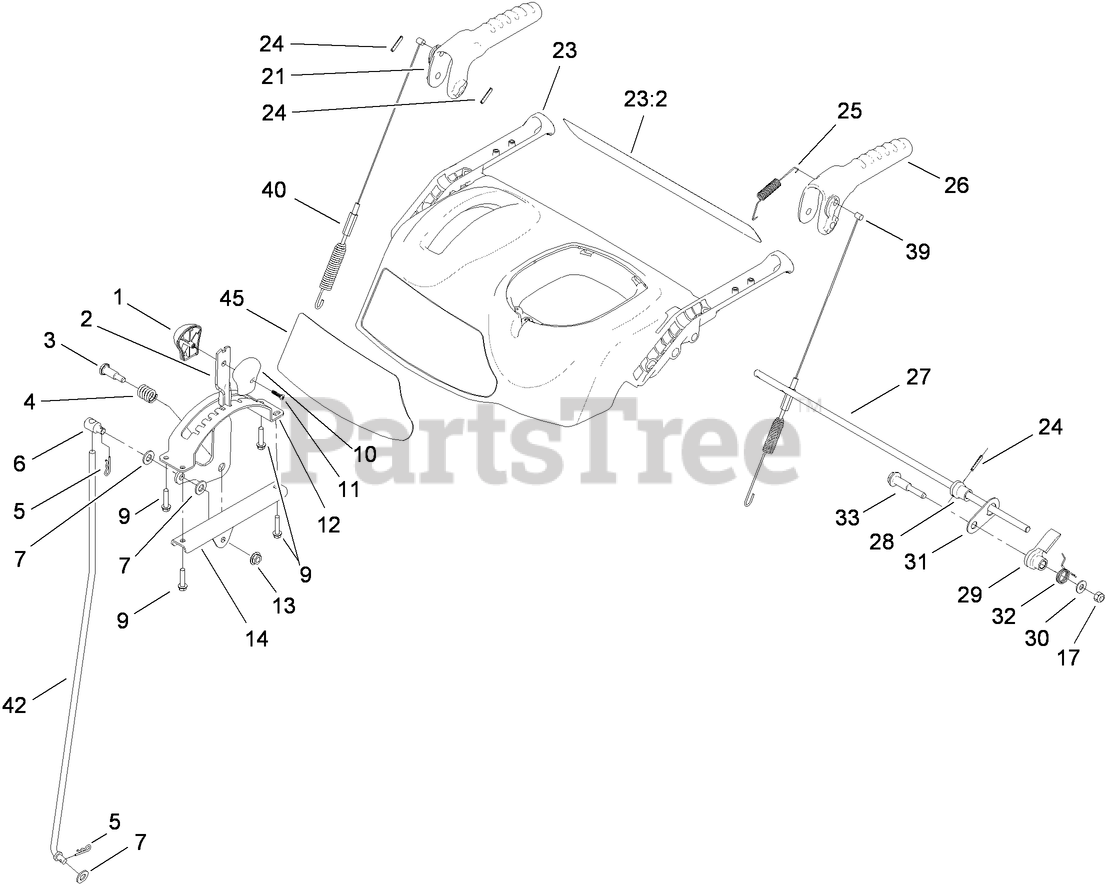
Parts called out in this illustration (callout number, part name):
1	KNOB-SHIFT, RH
2	SELECTOR-SPEED
3	SCREW-SHOULDER
6	TRUNNION-ROD
7	WASHER-FLAT
9	SCREW-PLASTITE
10	KNOB-SHIFT, LH
11	SCREW-PPH
12	GUIDE-SELECTOR, SPEED
13	NUT-HF
14	MOUNT-SELECTOR, SPEED
17	NUT-LOCK, NI
21	LEVER-AUGER
23	CONTROL PANEL ASM
23:2	DECAL-PANEL, CONTROL
24	PIN-SPRING
25	SPRING-TENSION
26	LEVER-TRACTION
27	ROD-LOCKOUT
28	CAM-LOCKOUT
29	LATCH-LOCKOUT
30	WASHER-FLAT
31	LINK-LOCKOUT
32	SPRING-TORSION
40	CABLE-AUGER
45	DECAL-CONTROL PANEL
